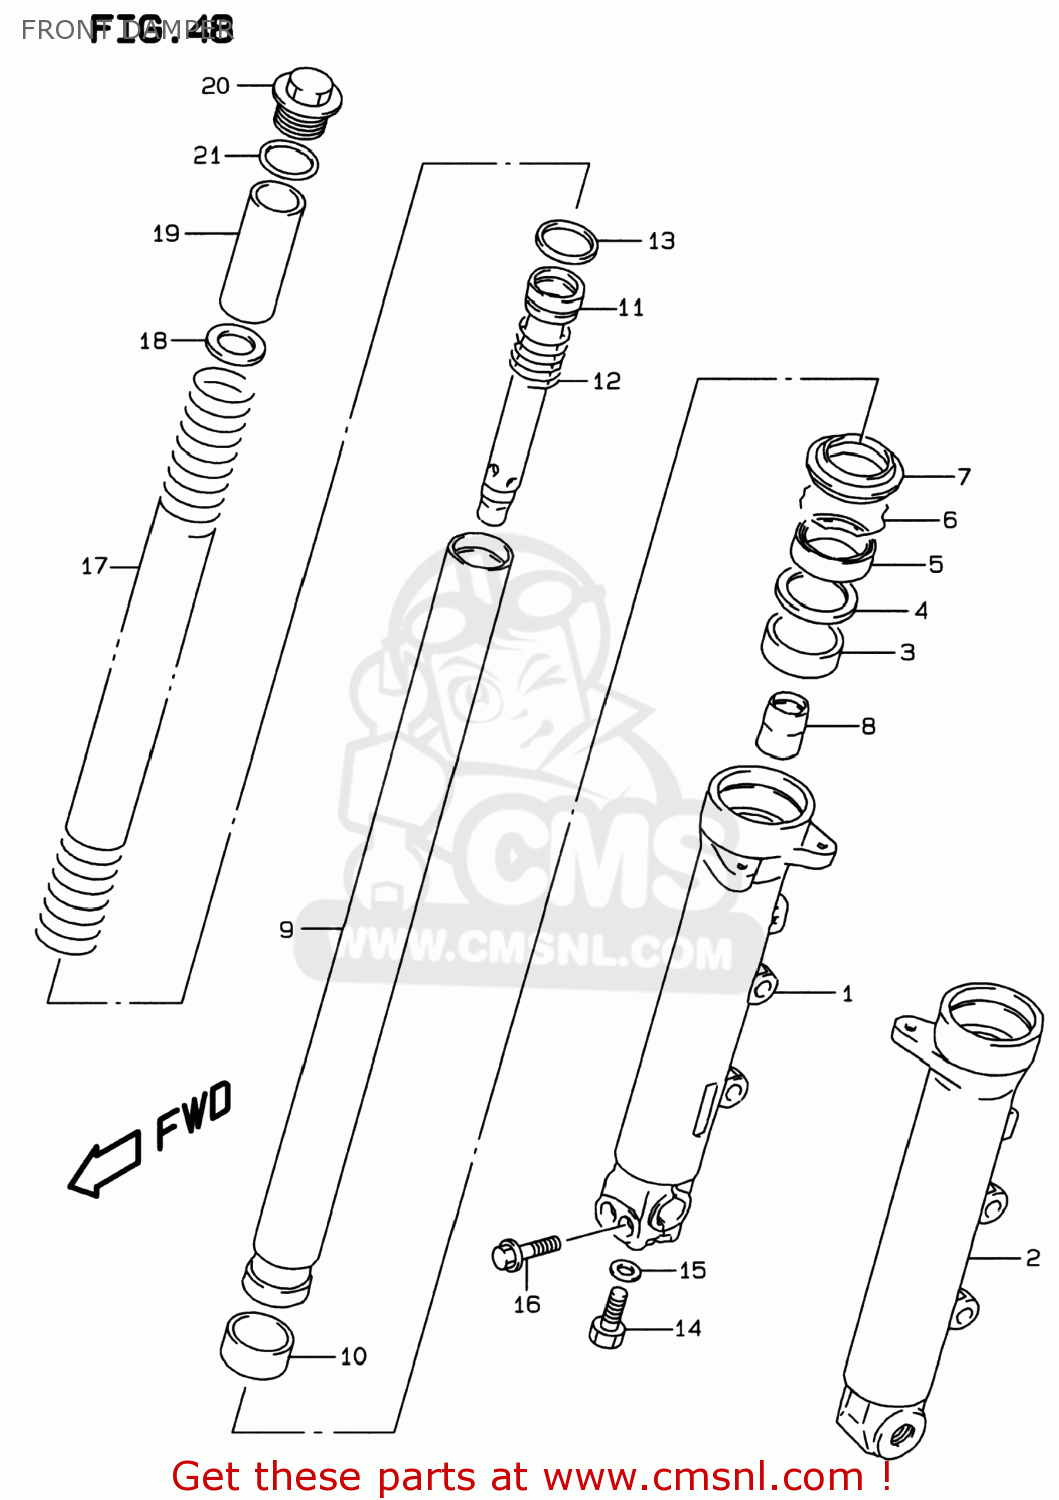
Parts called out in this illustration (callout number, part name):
1	TUBE,OUTER,R
2	TUBE,OUTER,L
3	METAL,SLIDE
4	WASHER,FORK OIL SEAL
5	SEAL,OIL
6	RING,OIL SEAL STOPPER
7	SEAL,DUST
8	PIECE,OIL LOCK
9	TUBE,INNER
10	PISTON
11	CYLINDER
12	SPRING,REBOUND
13	RING,PISTON
14	BOLT,FORK CYLINDER(10X25)
15	GASKET (NAS)
16	BOLT
17	SPRING,MAIN
18	WASHER(22.5X35.9X1.6)
19	SPACER,SPRING
20	CAP,FORK
21	O RING(D:3.5,ID:31.7)
